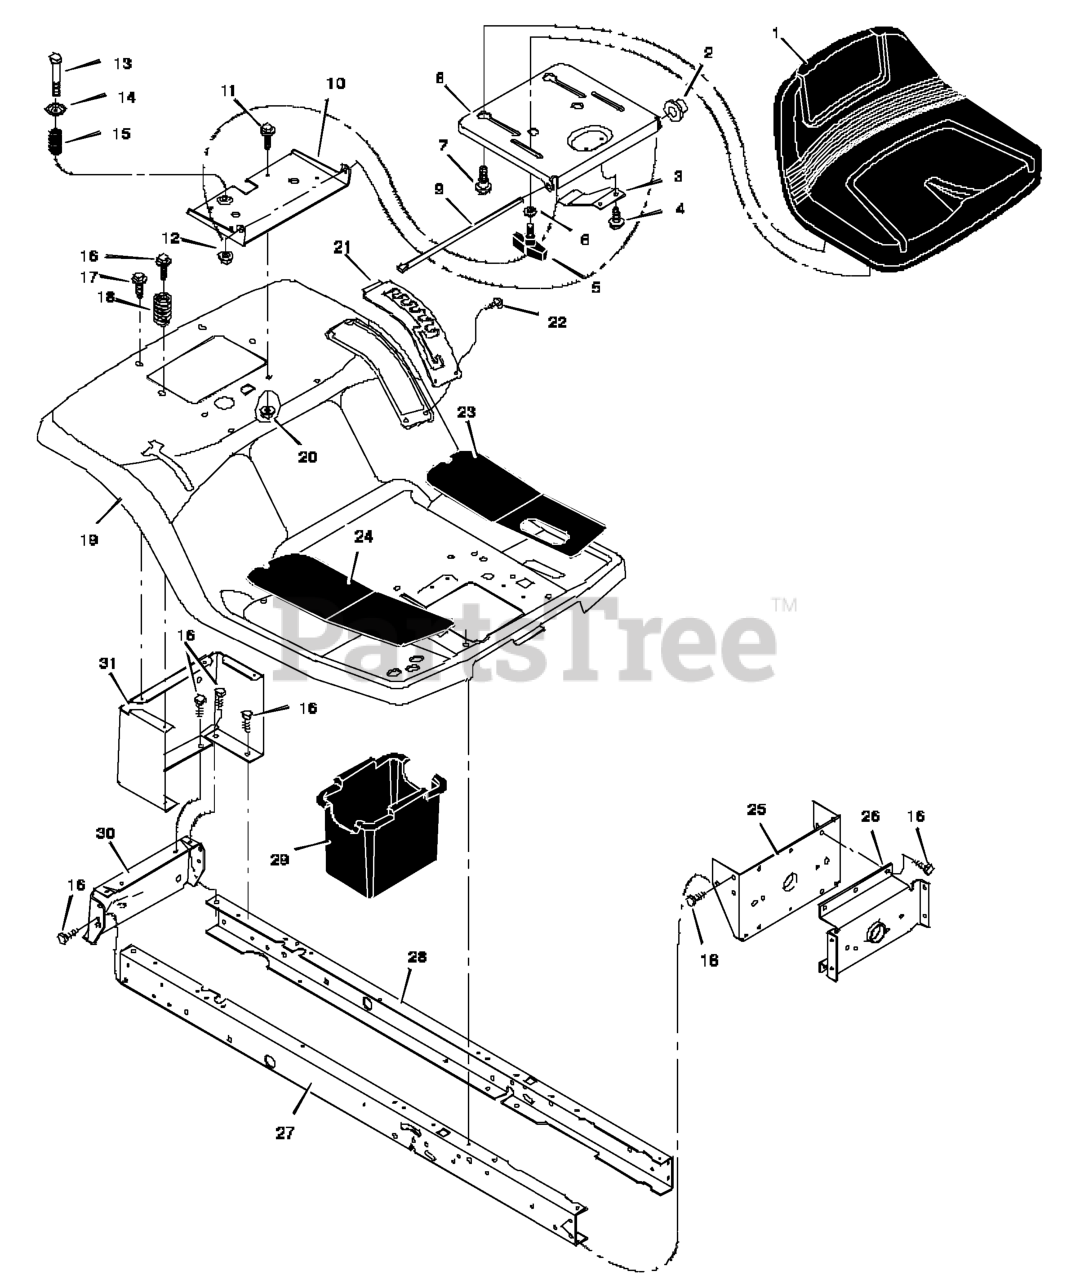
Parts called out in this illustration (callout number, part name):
2	Cap, Push On
4	Screw
5	Bolt, Wing
6	Washer
7	Bolt, Shoulder
8	Support, Seat
9	Rod, Pivot
10	Bracket, Pivot
11	Bolt
13	Bolt, Shoulder
15	Spring
19	Deck, Seat
20	Nut
21	Plate, Index
22	Screw
23	Mat, Left
24	Mat, Right
25	Bracket, Rear Hanger
26	Axle, Hanger
27	Frame, Right
28	Frame, Left
29	Container, Battery
30	Plate, Hitch
31	Panel, Rear
